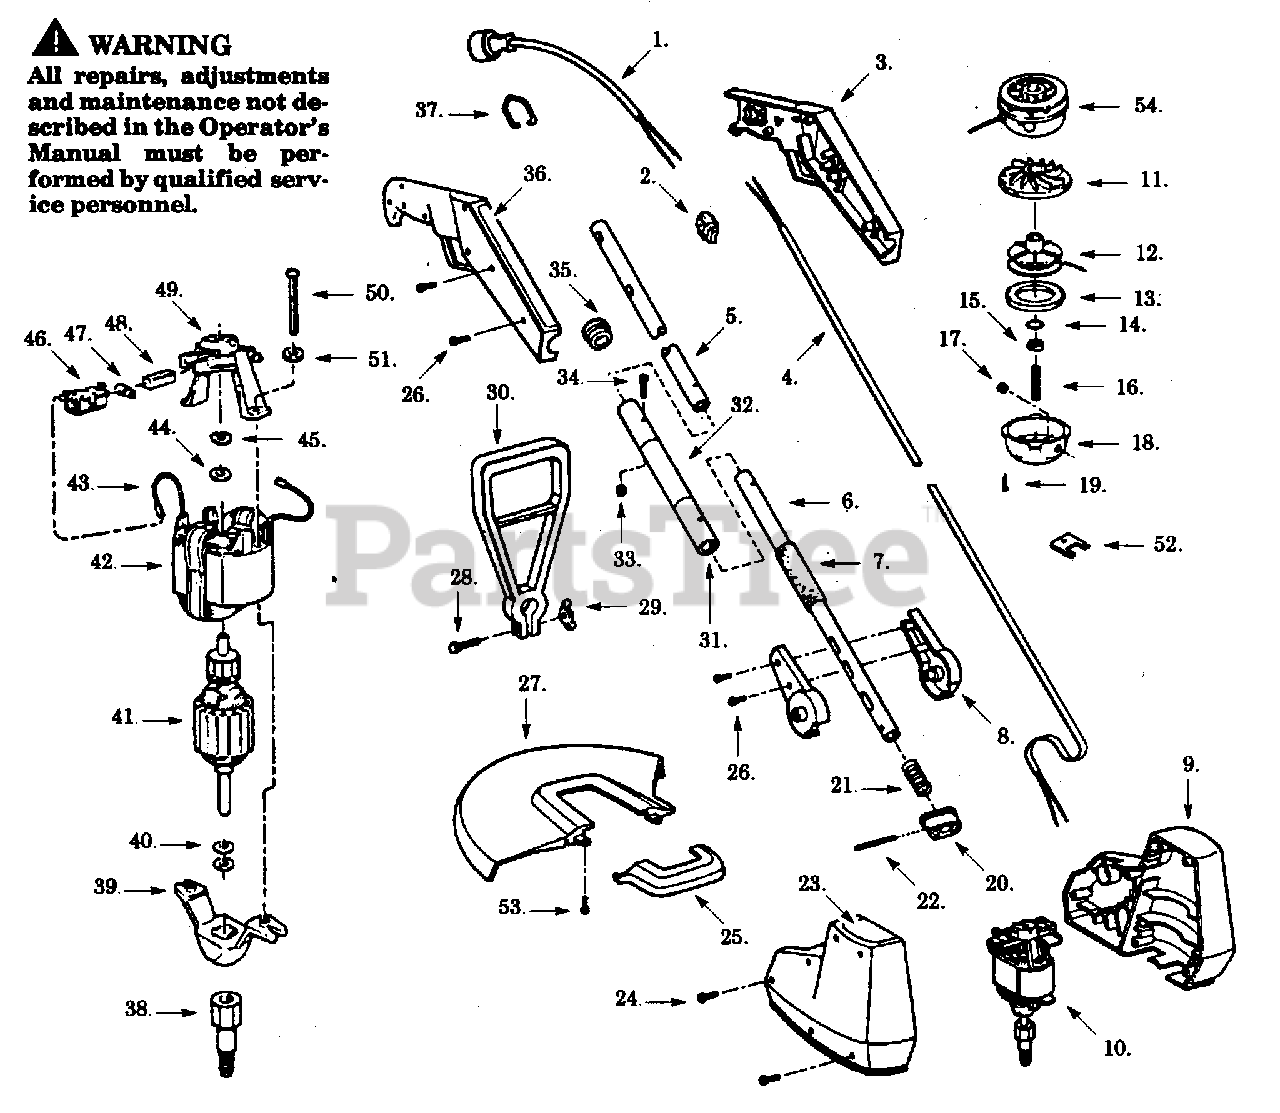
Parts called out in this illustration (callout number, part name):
1	Power Cord
2	Trigger Switch
3	R.H./L.H. Handle
5	Upper Tube
6	Lower Tube
7	Foam Grip
8	R.H./L.H. Pivot
9	R.H./L.H. Housing
10	Motor Ass'y.
11	Rear Plate
12	Spool & Line
13	Foam Pad
15	Adapter Nut
18	Hub Ass'y.
19	Cotter Pin
23	Hsg. Top Label
25	Front Guard
27	Guard & Blade Ass'y.
29	Wing Nut
30	Assist Handle
31	Outer Tube
32	Warning Label (Not a serviceable part)
33	Stop Nut
36	Handle Label
38	Shaft Adapter
39	Endbell Ass'y. (Drive)
41	Armature Ass'y.
42	Field Ass'y.
43	Lead Wire Ass'y.
45	Retaining Ring
46	Brush Holder
47	Brush Spring
49	Endbell Ass'y. (Brush)
51	Lockwasher
52	Spanner Wrench
54	Cutting Head Ass'y.
